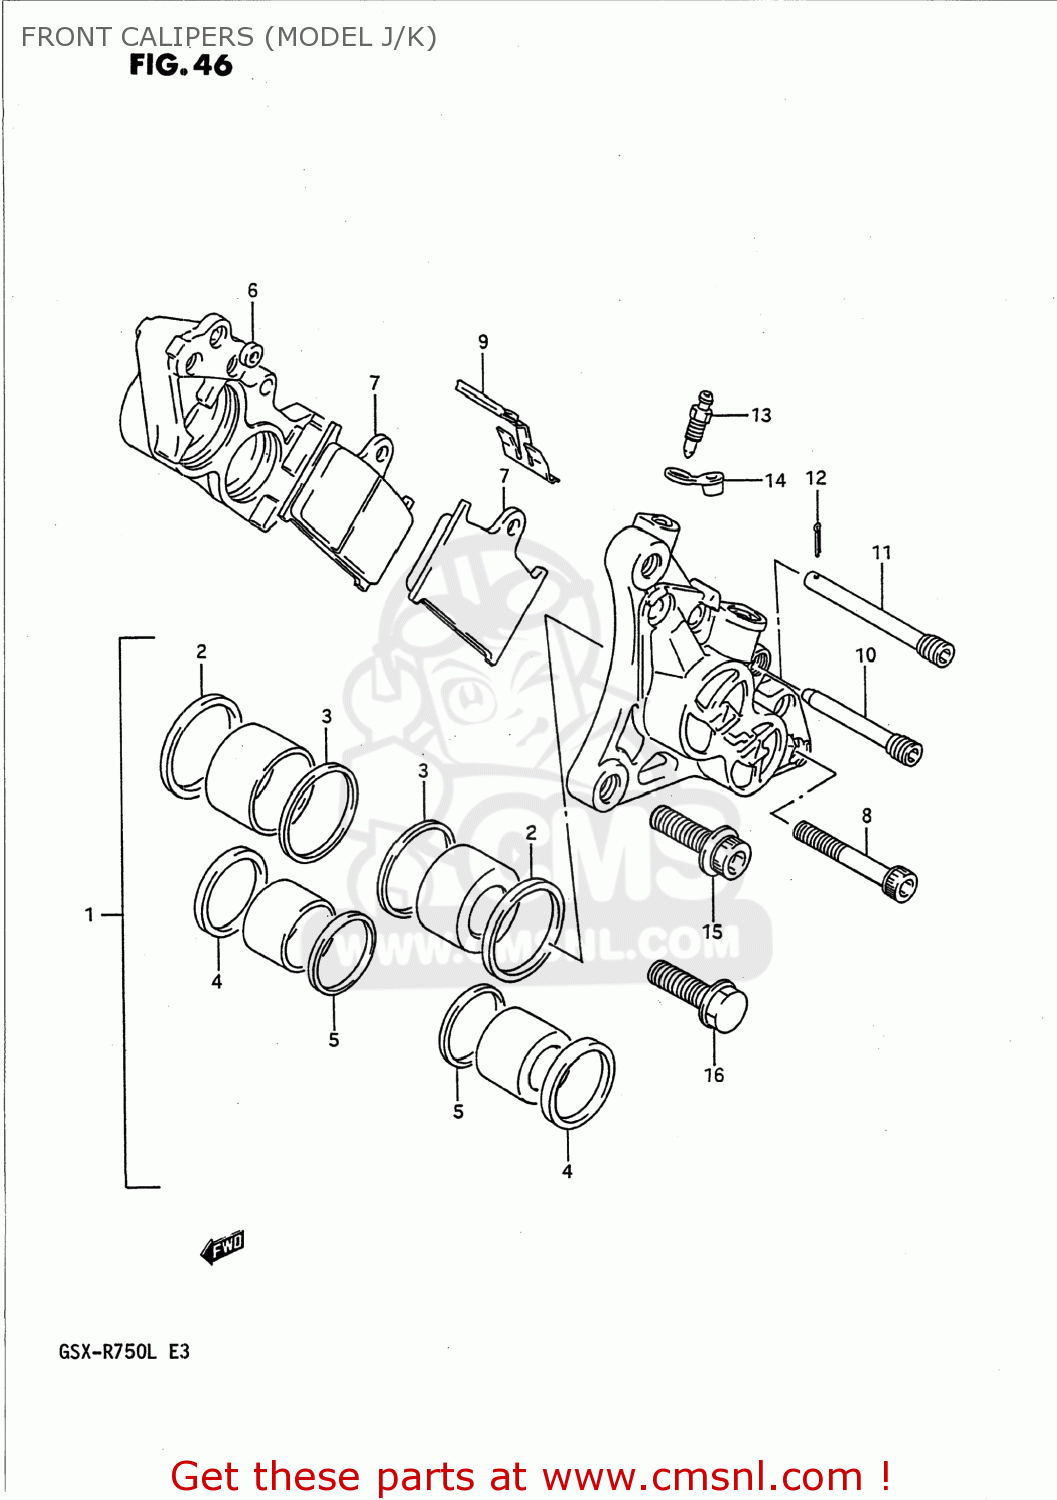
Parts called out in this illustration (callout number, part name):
1	PISTON SET
2	SEAL,PISTON
3	BOOT,PISTON
4	SEAL,PISTON
5	SEAL
6	SEAL
7	PAD
8	BOLT
9	SPRING
10	PIN,HOLDER
11	PIN,HANGER
12	COTTER PIN
13	BLEEDER
14	CAP,BLEEDER
15	BOLT
16	BOLT 10X30
